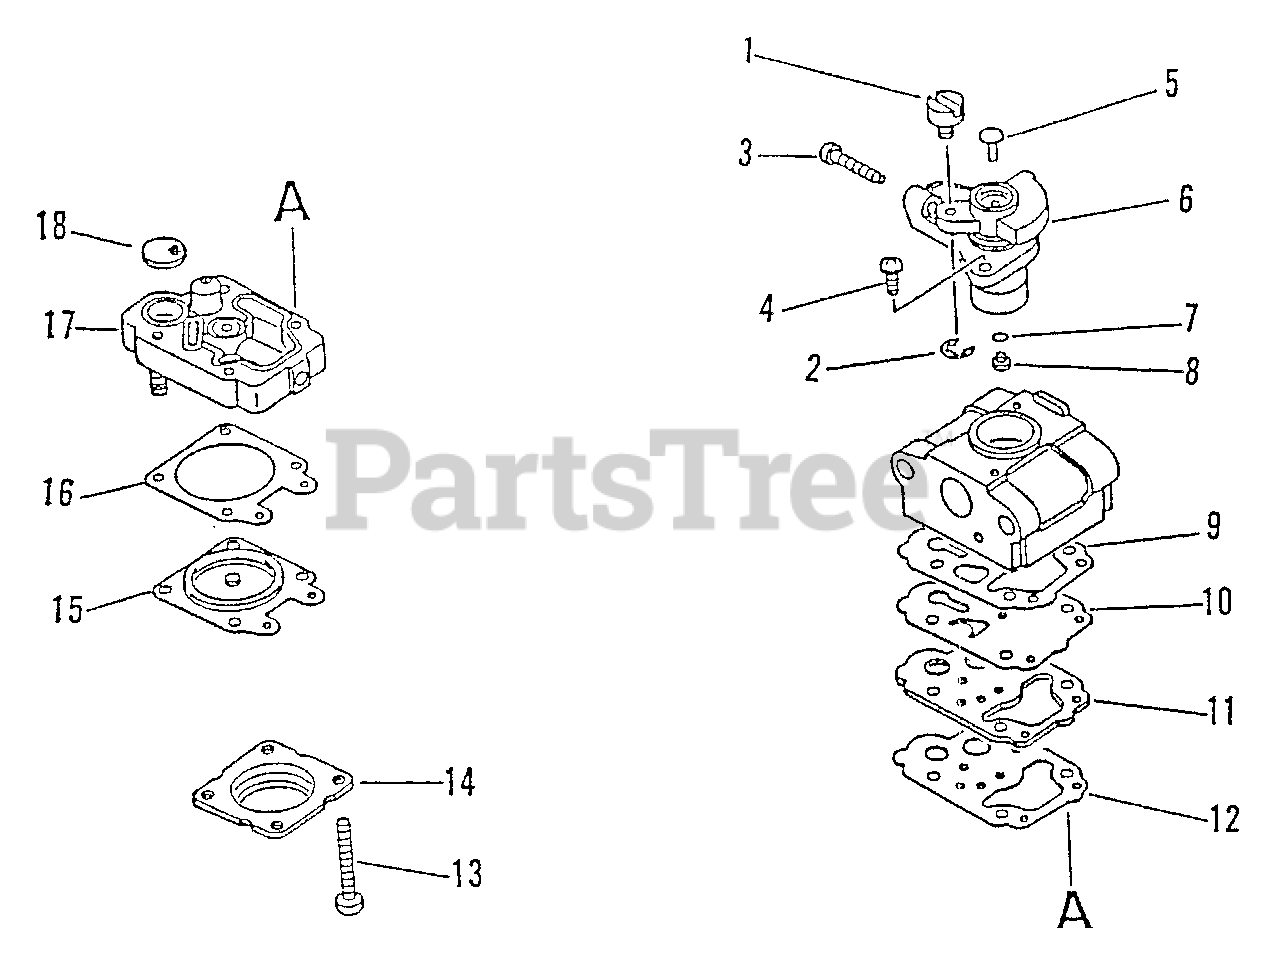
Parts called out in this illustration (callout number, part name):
2	RING, RETAINING
3	SCREW, IDLE ADJUST
5	PLUG, WELCH
6	THROTTLE VALVE ASSY
7	O-RING
8	JET
9	GASKET, PURGE
10	DIAPHRAGM, PURGE
11	PLATE, PUMP
12	GASKET, PLATE
14	COVER, METERING
15	DIAPHRAGM, METERING
16	GASKET, METERING
17	BASE, PURGE
18	STRAINER
